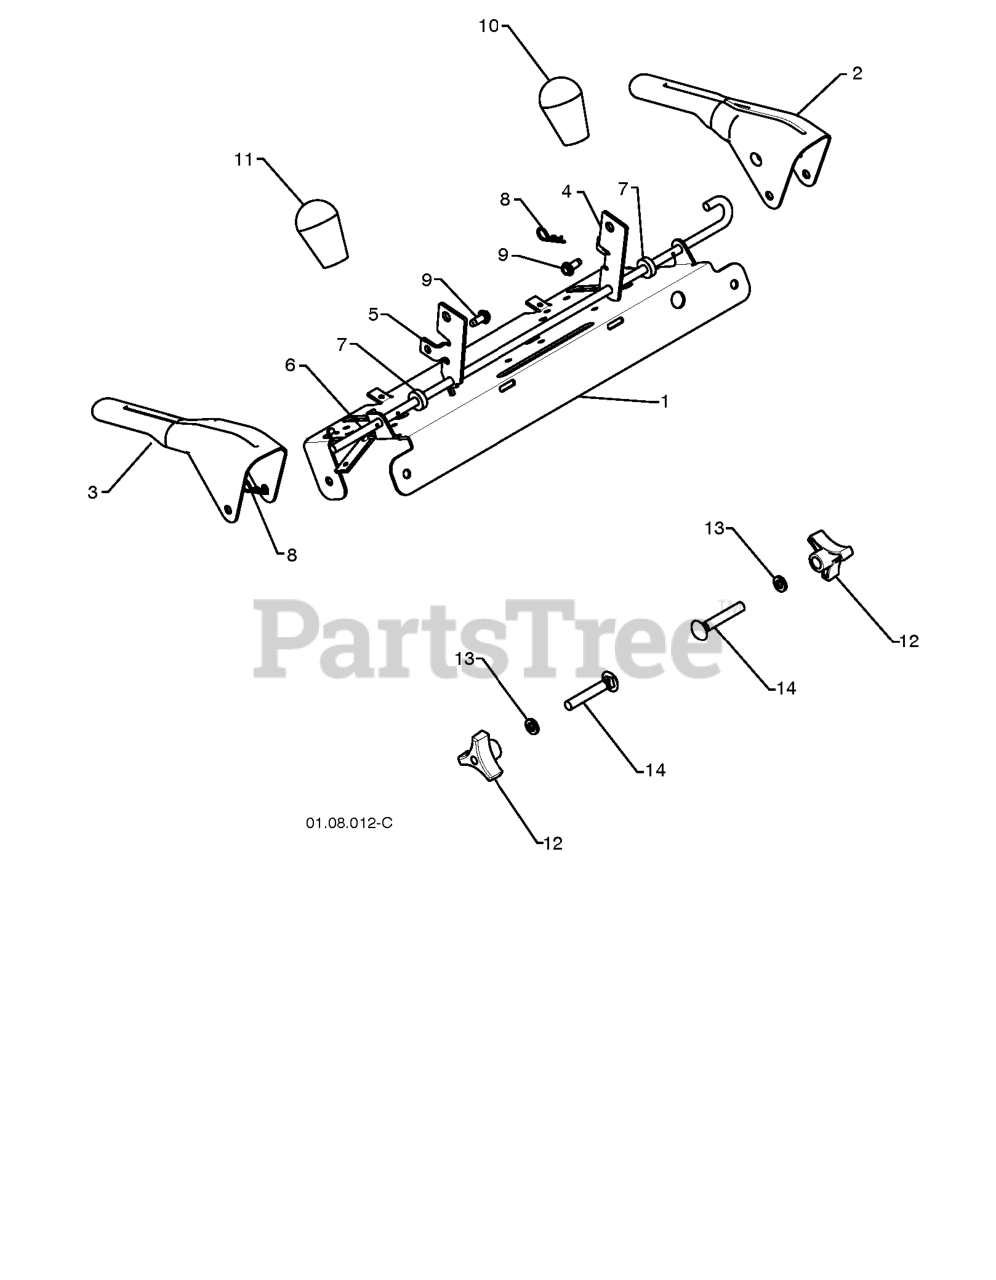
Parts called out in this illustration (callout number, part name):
1	PANEL.CONTROL.PNT.BLACK
2	LEVER.CONTROL.LH.BLACK
3	LEVER.CONTROL.RH.GREY
4	ARM.TRACTION.ROD.YZ
5	ARM.IMPELLER.ROD.SNOW
6	BAIL.CONTROL.INTERLOCK
7	SPACER.CONTROL.LEVER
8	SPRING RETAINER
9	SCREW 14-20 X 5/8
10	KNOB LEVER, BLACK
11	RED KNOB SHIFTER
12	KNOB.HANDLE.3/8.TRI-POINT.BLAC
13	WASHER
14	BOLT 3/8-16 X 2-1/4
